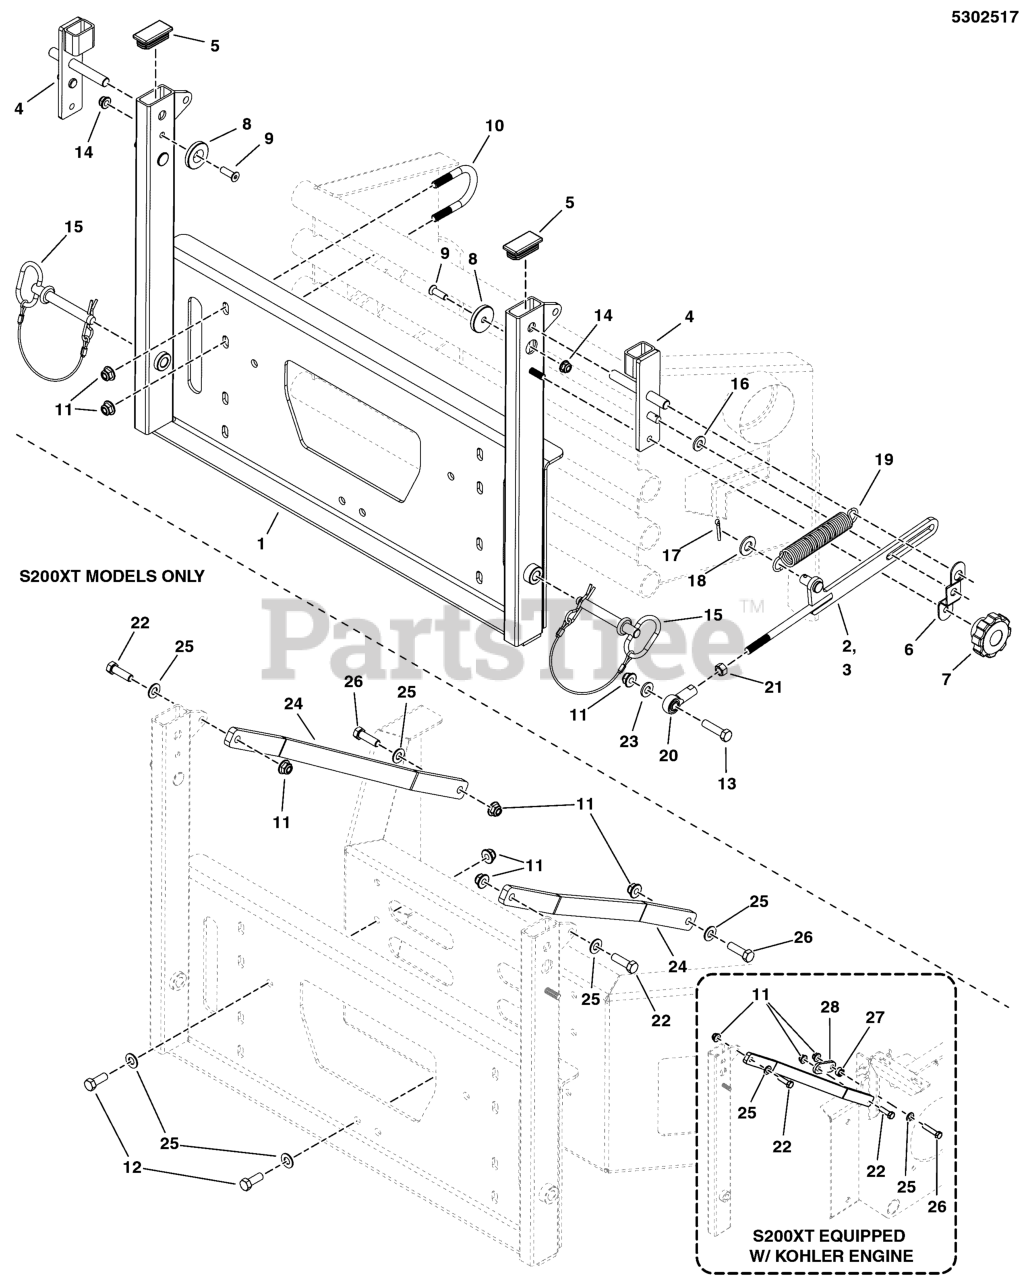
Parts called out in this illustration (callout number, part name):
1	WELD, MOUNT ASSY, 3100Z/200X-XT - BLK
1	WELD, HOPPER MOUNT, IS3200Z - BLK
2	WELD, LATCH BAR, IS3100/200XT, CZ
3	WELD, LATCH BAR, IS3100/200XT, CZ
4	WELD, PIN LOCK, HOPPER - BLK
5	PLUG, 1 X 2, 10-14 GA. TUBING
6	PLATE, PIN LOCK - BLK
7	KNOB-INT THR .312-18 4-ARM 2.12WD 1.06LG
8	SPACER, .34 X 1.54 X .25 UHMW
9	SCREW, 5/16-18 X 1, PHILLIPS HD, BZ
10	U-BOLT, 3/8 X 1-1/4
11	NUT, 3/8-16 HEX NYLOCK FLANGE
12	BOLT, 3/8-16 X 1" GD5 CZ
13	BOLT, 3/8-16 X 1-1/2" GD5 CZ
14	NUT, 5/16-18 HEX NYLOCK FLANGE
15	PIN, HITCH, .50 X 3.25 W/ LAY
16	WASHER, 3/8 X 1 X 1/16, NYLON F/W
17	PIN, 3/32 X .750, COT, ZINC/CLEAR
18	WASHER, 1/2 SAE
19	SPRING, EXTENSION, 1.00
20	BALL JOINT, 3/8-24 FEMALE
21	NUT, 3/8-24 HEX JAM
22	BOLT, 3/8-16 X 1-1/4" GD5 CZ
23	WASHER, 3/8 GD.9 FLAT
24	BAR, STAY STRAP, 200X - BLK
25	WASHER, 3/8 SAE
26	BOLT, 3/8-16 X 1-3/4" GD5 CZ
27	SPACER, .39 X .75 X .38
28	PLATE, EXTENSION - BLK
